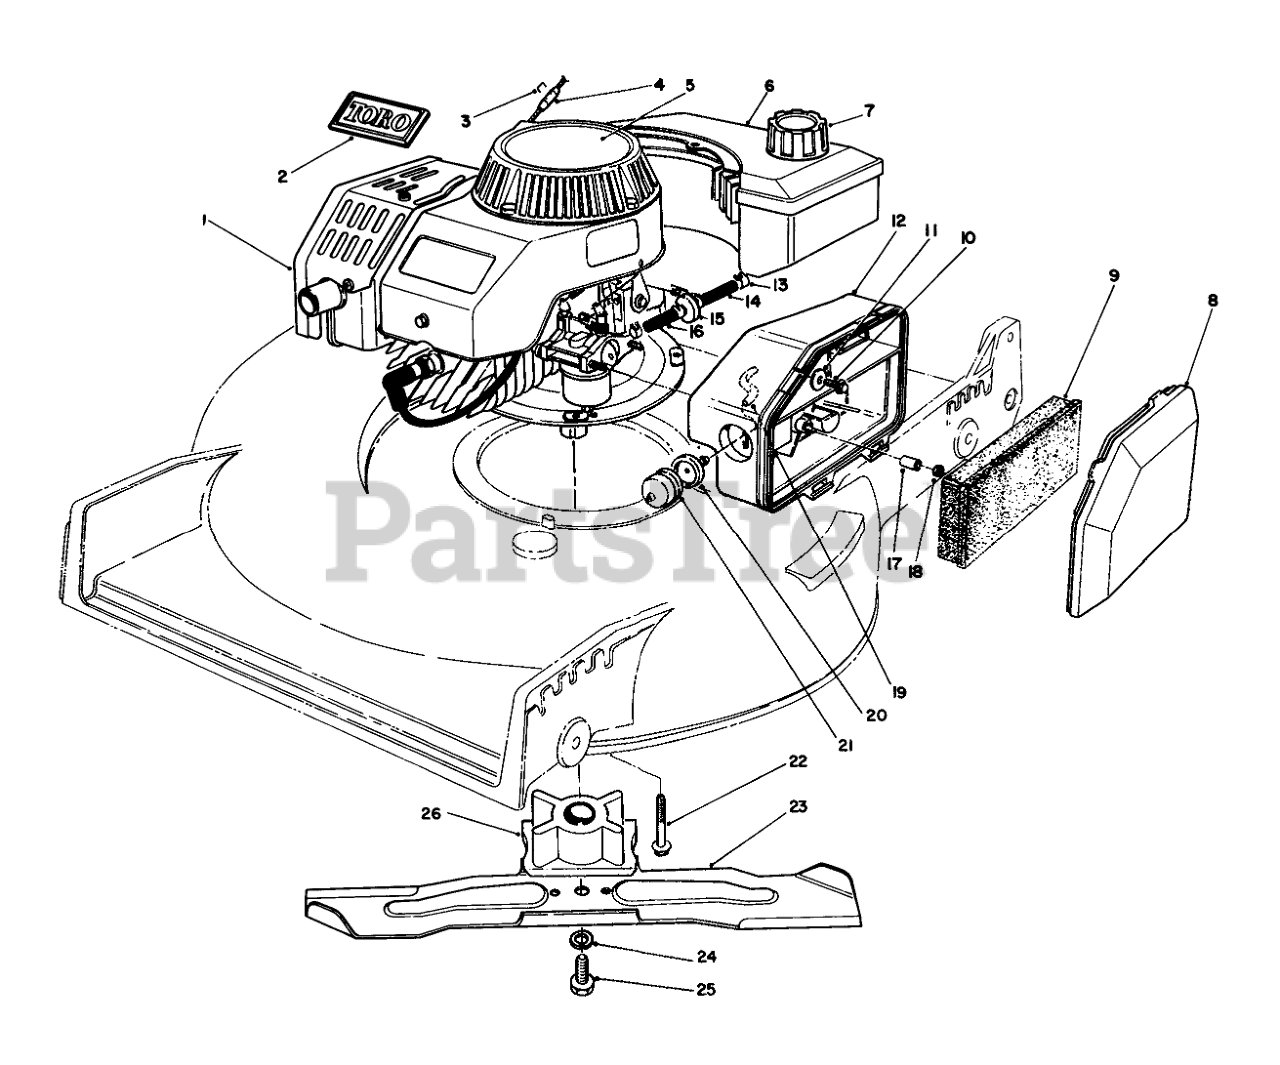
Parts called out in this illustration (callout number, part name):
1	Engine
2	TORO LOGO PLT
3	Staple
5	DECAL
6	Gas Tank Assembly
7	GAS CAP ASM
8	COVER-AIR CLEANER
9	ELEMENT-AIR CLEANER
10	SCREW-HH
11	WASHER-FLAT
12	BODY-AIR CLEANER
13	CLAMP-FUEL LINE
14	HOSE-FUEL
15	FILTER-FUEL
16	HOSE-FUEL
17	SPACER
19	HOSE-PRIMER
20	BODY-PRIMER
21	Bulb Primer
22	SCREW-HHF
23	BLADE-21in
24	WASHER-LOCK
25	SCREW-BLADE
26	BLADE RETAINER
